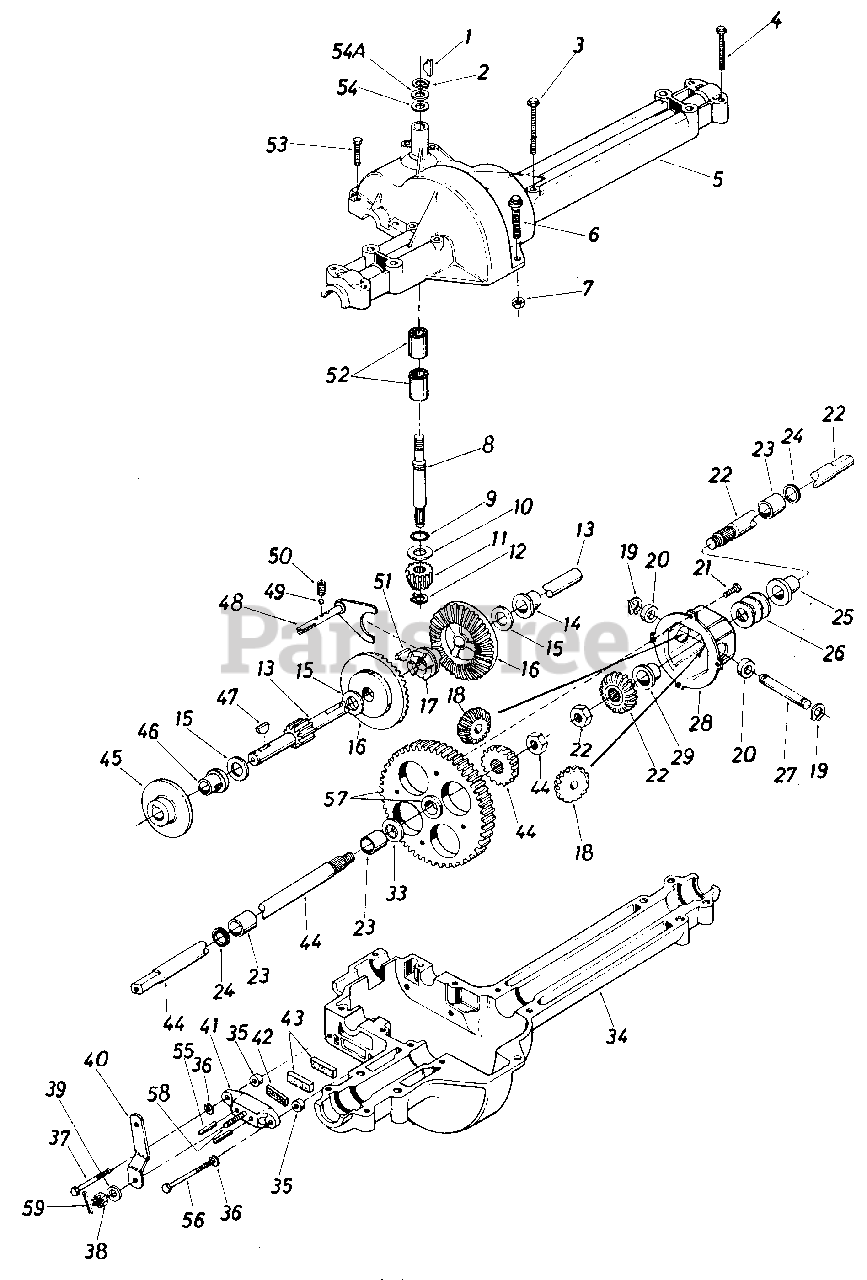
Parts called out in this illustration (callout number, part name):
1	#4 Hi-Pro Key 3/32 x 518" Dia.
2	Snap Ring .625" Shaft
3	Hex Bolt 1/4-20 x 1.75" Lg.
4	Hex Bolt 1/4-20 x 1.25" Lg.
5	Upper Housing
6	Hex Fl-Bolt 1/4-20 x .88" Lg.
7	Hex Nut 1/4-20 Thd.
8	Input Shaft
9	Square Seal 518" I.D.
10	Thrust Washer 518" I.D. x 1 25" O.D
11	Pinion Input 14T
12	Retaining Ring 7/16" Ext.
13	Drive Shaft
14	Flange Brg. 5/8" I.D. x 3/4"
15	Fl-Wash.
16	Bevel Gear 42T
17	Clutch Collar
18	Miter Gear 15T (H.D.)
19	Snap Ring
20	Thrust Bearing 1/2" I.D. x 1.0" O.D.
21	Pan Head Scr. 1/4-20 x .50" Lg. w/Patch
22	Axle R.H. Ass'y. Kit
23	Sleeve Bearing 3/4" I.D. x 1.0" Lg.
24	Oil Seal 3/4" I.D.
25	Flange Bearing 3/4" I.D. x 15/16" Lg.
26	Fl-Wash. .760" I.D. x 1.49" O.D.
27	Cross Shaft
28	Differential Housing Ass'y.
33	Fl-Wash. .760" I.D. x 1.49" O.C.
34	Lower Housing
35	Spacer .53" O.D. x 3/8" Lg.
36	L-Wash. 1/4" I.D.
37	Hex Bolt 1/4-20 x 1.50" Lg. (Grade 5)
38	Castle Nut 5/16-24 Thd.
39	Fl-Wash. .344" I.D. x .875" O.D.
40	Actuating Arm
41	Brake Yoke
42	Puck Plate
43	Brake Puck
44	Axle L.H. Ass'y. Kit
45	Brake Disc
46	Flange Bearing 518" I.D. x 15/16" Lg.
47	Woodruff Key 3/16 x 5/8 HT
48	Shift Fork Ass'y.
49	Ball Detent .250" Dia.
50	Spring Detent
51	#9 Hi-Pro Key 3/16 x 3/4" Dia. HT
52	Needle Brg. 5/8" I.D. x 1/2" Lg.
53	Hex Bolt 1/4-20 x 1.00" Lg.
54	Fl-Wash. 5/8" I.D. x .030
54A	Fl-Wash. 518" I.D. x .040
55	Actuating Pin 5/16" Dia.
56	Hex Bolt 1/4-20 x 2.50" Lg. (Grade 5)
57	Differential Gear 72T Ass'y. w/Bearing
58	Sq. Hd. Bolt 5/16-24 Thd.
59	Cotter Pin 3/32" Dia. x .50" Lg.
